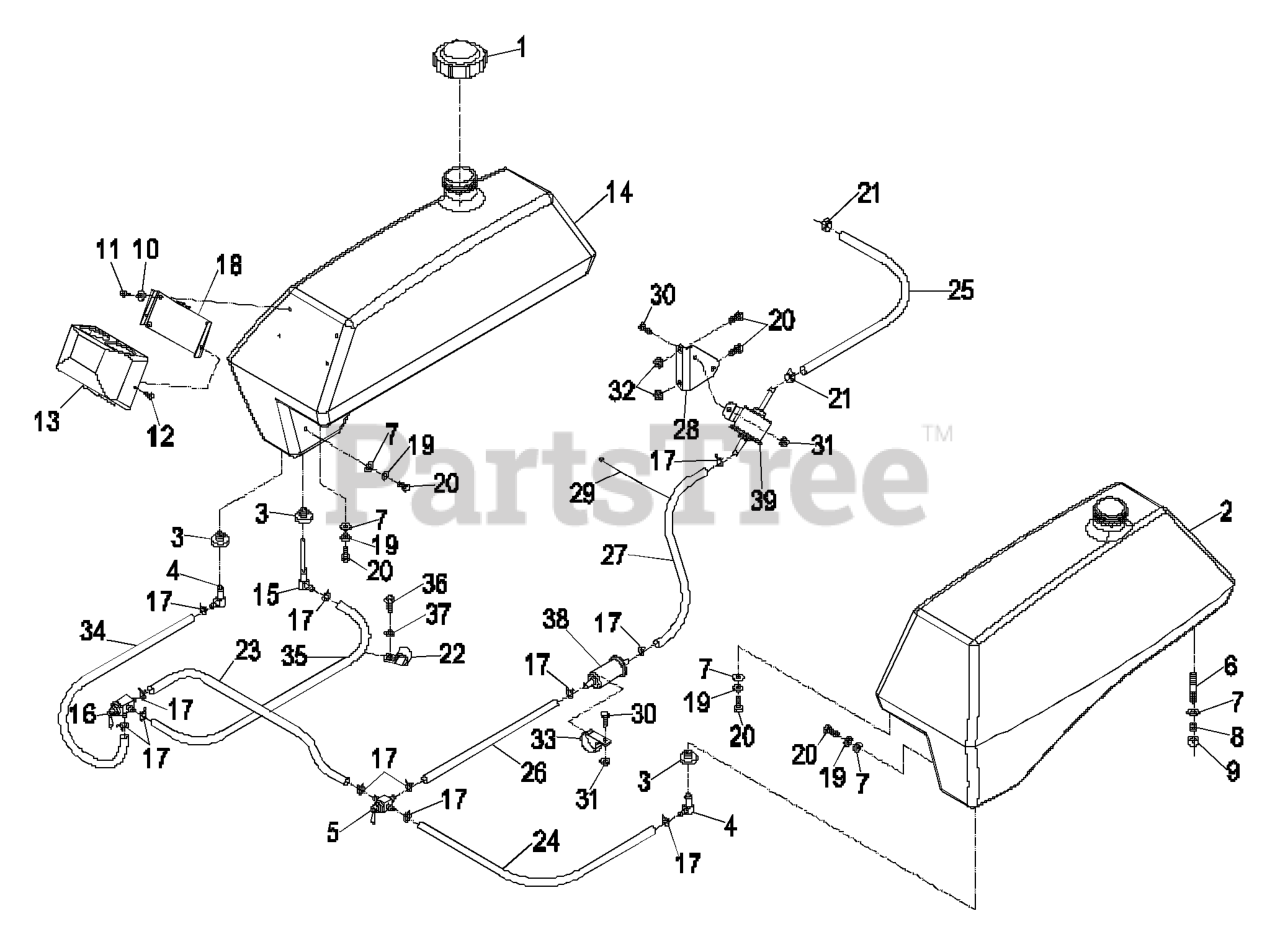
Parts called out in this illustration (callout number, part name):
1	CAP-FUEL
4	ELBOW-90 DEG
5	VALVE-FUEL
6	STUD
7	WASHER-PLAIN
8	SPRING-TANK, FUEL
9	NUT-LOCK, NI
10	WASHER-SPRING
11	SCREW-PPH
13	COVER,GAUGES
16	VALVE,FUEL DIVERTER 90 DE
18	BRACKET,GAUGE MOUNT
19	WASHER-LOCK
20	SCREW-HH
21	CLAMP-HOSE, FUEL
22	CLIP-LOOM
24	FUEL LINE,19.0
25	HOSE-FUEL
26	FUEL LINE
27	HOSE-FUEL
29	TIE-PLASTIC
30	SCREW-HH
33	CLIP,LOOM 1.69 DIA
34	HOSE-FUEL
36	SCREW-HH
37	WASHER-LOCK
38	Fuel Filter
39	Fuel Pump
